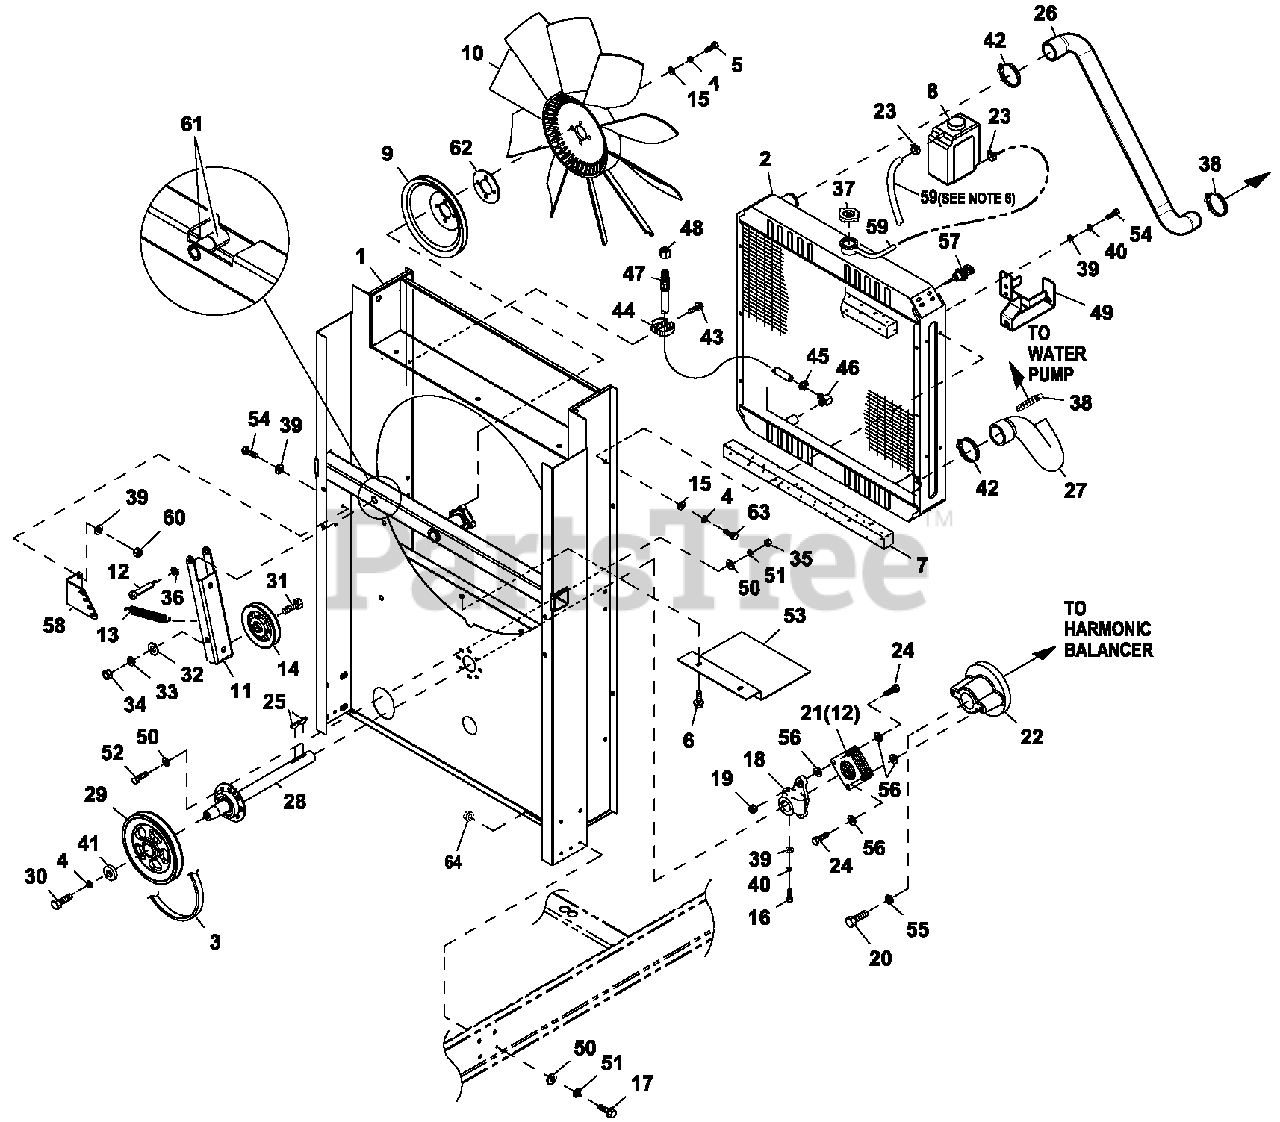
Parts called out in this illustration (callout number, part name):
1	WELDMENT RADIATOR SUPPORT C5
2	RADIATOR 680 X 680 X 70 CPL
3	V-BELT 31/64" X 62-3/8"
4	WASHER LOCK M10
5	SCREW HHC M10-1.5 X 30 C10.9
6	SCREW THF M6-1 X 16 N WA Z/JS
7	TAPE FOAM 1 X 1 (26.75" LG)
8	TANK COOLANT RECOVERY
9	PULLEY FAN V-GROOVE 9"
10	FAN 26" LH ROTATION
11	ARM BELT TENSIONER
12	SHOULDER BOLT 1/2 X 2-1/4"
13	SPRING TENSION CPL
14	PULLEY V-BELT 4" FLANGED
15	WASHER FLAT 3/8-M10 ZINC
16	SCREW HHC M8-1.25 X 45 C8.8
17	SCREW HHFC M6-1.0 X 20 G8.8
18	HUB FLEX PLATE
19	NUT HEX LOCK 5/16-24 NY INS
20	SCREW HHC M12-1.5 X 60 G8.8
21	DISK FLEX
22	COUPLING FLEX HUB MACHINED
23	CLAMP HOSE BAND 1/4
24	SCREW HHC 5/16-24 X 1.124
25	KEY WOODRUFF 4 X 19D
26	HOSE RADIATOR UPPER C5 CPL
27	HOSE RADIATOR LOWER C5 CPL
28	ASSY BRG/SHAFT CPL FANDRIVE
29	PULLEY 5.5" DIA MACHINED
30	SCREW HHC M10-1.5 X 30 G8.8
31	SCREW HHC 1/2-13 X 2" G8
32	WASHER FLAT 1/2 ZINC
33	WASHER LOCK 1/2
34	NUT HEX 1/2-13 STEEL
35	NUT HEX M6 X 1.0 G8 YEL CHR
36	WASHER NYLON .50 X .87 X .06
37	CAP RADIATOR 13 PSI
38	CLAMP HOSE #24 B1.06-2.00
39	WASHER FLAT 5/16-M8 ZINC
40	WASHER LOCK M8-5/16
41	SPACER .5 X 1.5 X .25 STL/ZINC
42	CLAMP HOSE #28 1.32-2.25
43	SCREW HHTT M4-0.7 X 8 BP
44	SPRING CLIP HOLDER .37-.62
45	CLAMP HOSE .38-.87
46	BARBED EL 90 3/8 NPT X 3/8
47	HOSE DRAIN ASSY 28"
48	CAP HEX 1/4 NPT BRASS
49	BRACKET COOLANT TANK
50	WASHER FLAT 1/4-M6 ZINC
51	WASHER LOCK M6-1/4
52	SCREW HHC M6-1.0 X 20 G8.8
53	SHIELD RADIATOR
54	SCREW HHC M8-1.25 X 20 G8.8
55	WASHER LOCK M12
56	WASHER FLEX (THIN)
57	PROBE COOLANT LEVEL 3/8-18NPTF
58	BRACKET TENSIONER SPRING
59	HOSE 9/32 ID (43"LG)
60	NUT HEX LOCK M8-1.25 NY INS
61	BEARING SLEEVE 1/2/ X 3/4 X 1
62	SPACER CPL COOLING FAN 1/8"
63	SCREW HHC M10-1.5 X 20 C8.8
64	NUT FLANGE M6-1.0 NYLOK
